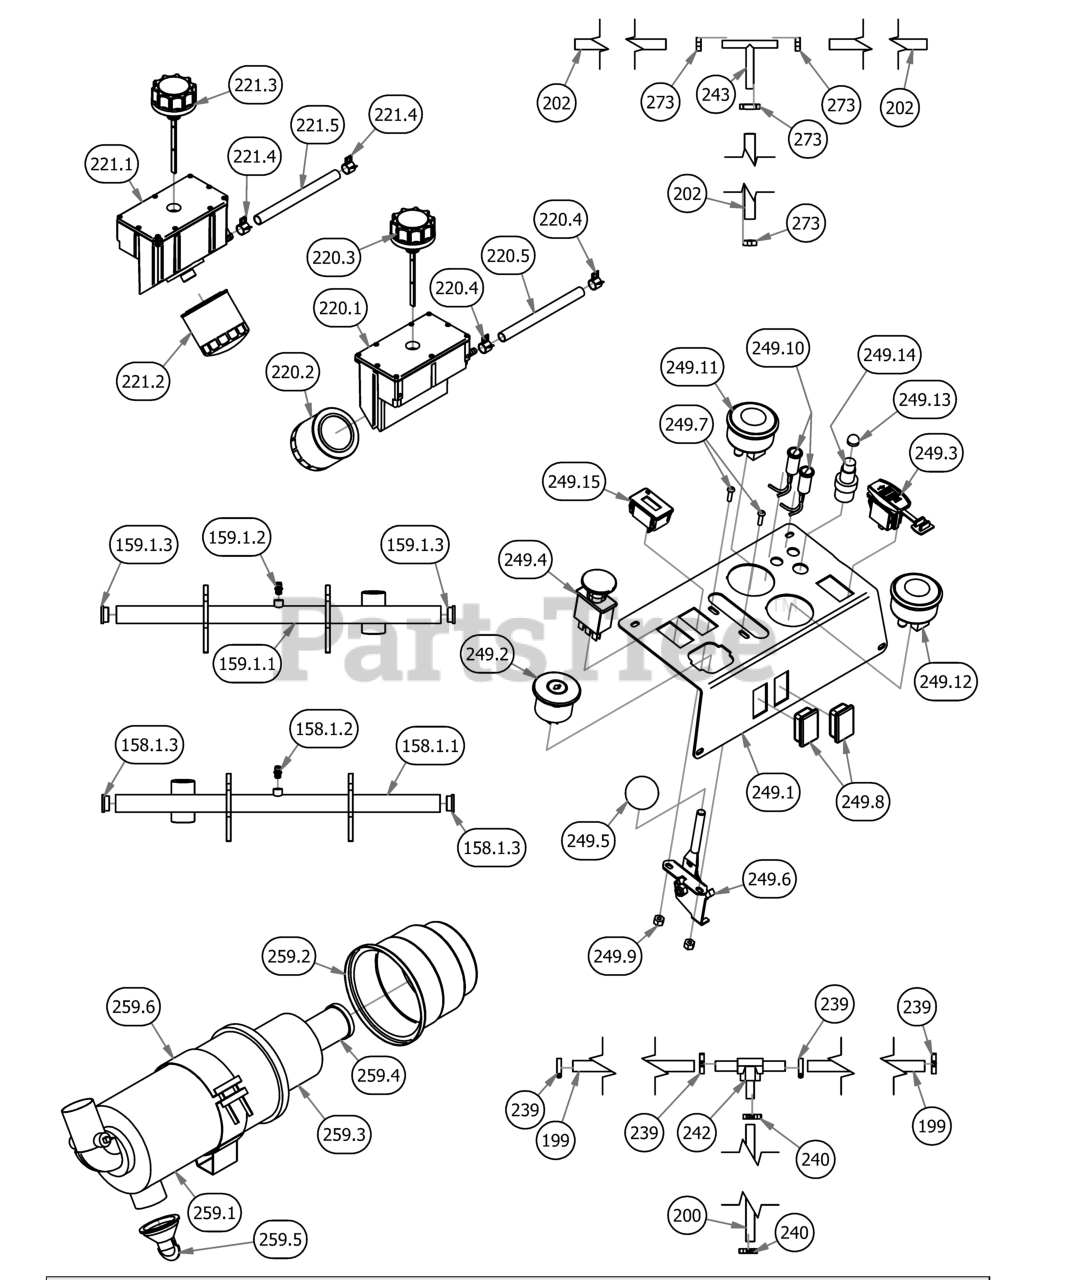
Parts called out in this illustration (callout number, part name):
158.1	2019 Drive Arm Actuator right
158.1.1	2019 Drive Arm Actuator right - Weldment
158.1.2	1/4" Press in Grease Fitting
158.1.3	2019 Drive Arm Bushing
159.1	2019 Drive Arm Actuator left
159.1.1	2019 Drive Arm Actuator left - Weldment
159.1.2	1/4" Press in Grease Fitting
159.1.3	2019 Drive Arm Bushing
199	1/4 Fuel Line Hose - Priced Per Foot
200	3/16 Fuel Line x 36"
202	5/16 Fuel Line Hose - Priced Per Foot
220	LH Rogue Hydro Tank Assy
220.1	2019 Left Outlaw Gen2 Hydro Tank Suspension Only
220.2	Hydraulic Filter
220.3	Hydraulic Tank Cap W/Dipstick
220.4	1/2 Hose Clamp
220.5	1/2 Clear Braded Hose Priced/Foot
221	RH Rogue Hydro Tank Assy
221.1	2019 Right Outlaw Gen2 Hydro Tank Suspension Only
221.2	Hydraulic Filter
221.3	Hydraulic Tank Cap W/Dipstick
221.4	1/2 Hose Clamp
221.5	1/2 Clear Braded Hose Priced/Foot
239	1/4 Fuel Hose Clamp
240	3/16 Vinyl Clamp
242	Brass fuel line T
243	5/16 x 5/16 x 1/4 Fuel Line T
249	Renegade Control Panel Assembly
249.1	2019 Diesel Control Panel
249.2	Ignition Switch
249.4	PTO Switch
249.5	Throttle Knob
249.6	Universal Throttle Head
249.7	10-24 X 5/8 BS Button Head Bolt
249.8	Light Plug
249.9	10-24 Nylon Insert Locknut
249.11	2" Oil Pressure Gauge
249.12	2" Water Temperature Gauge
249.13	Start Switch Boot - Diesel
249.14	Momentary Start Switch
249.15	Hour Meter
259	Enginaire Canister VLR-Complet
259.1	Canister for All Diesel Models
259.2	Enginaire Air canister cap
259.3	Diesel Air Filter- Outer
259.4	Diesel Air Filter- Inner
259.5	Debris Plug-Enginaire Filter
259.6	Mounting Bracket For Diesel Air Filter
273	2 EAR CLAMP 12.5mm-15mm
